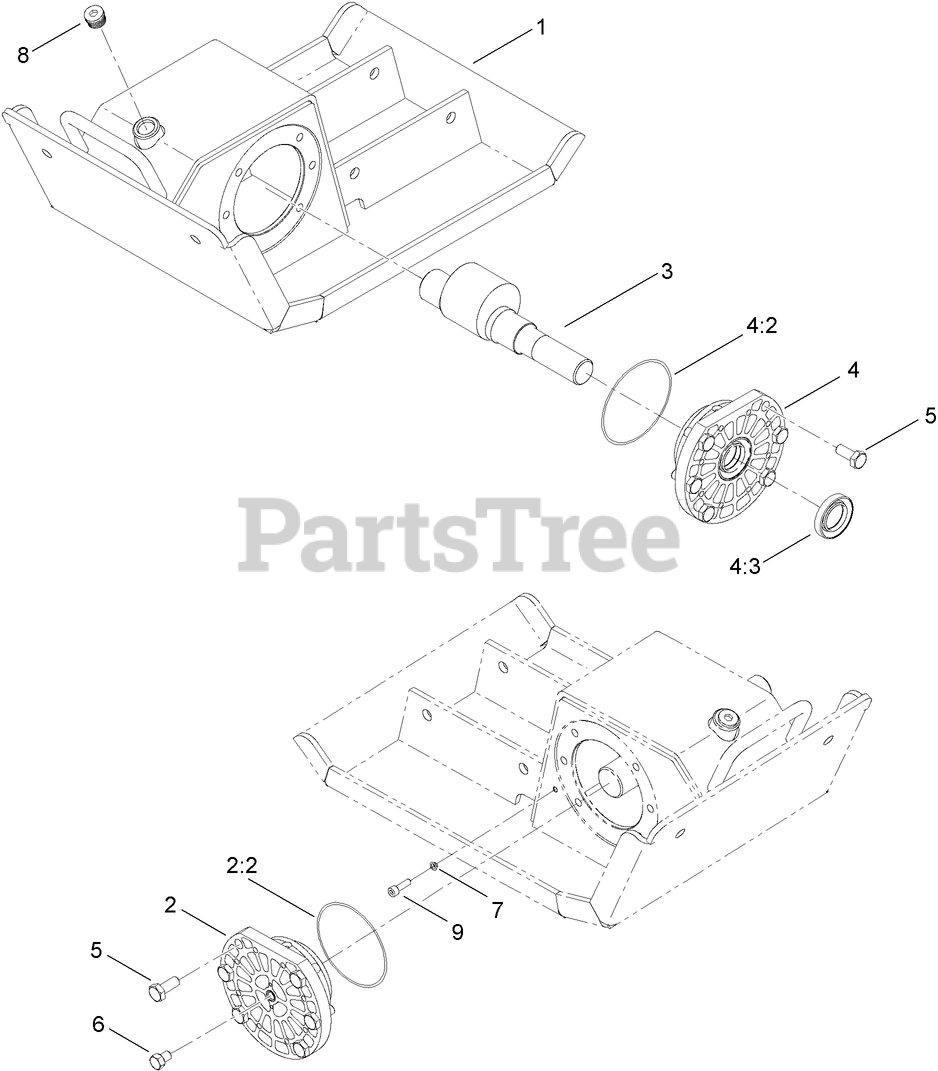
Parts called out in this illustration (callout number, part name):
1	BASE
2	PLATE CAP BEARING ASM (BLIND END)
2:2	O-RING
3	SHAFT-ECCENTRIC
4	PLATE CAP BEARING ASM (SHEAVE END)
4:2	O-RING
4:3	SEAL-SHAFT
5	SCREW-HH
6	SCREW-HH
7	WASHER-SEALING, NYLTITE
8	FITTING-HYD
9	SCREW-HSH
